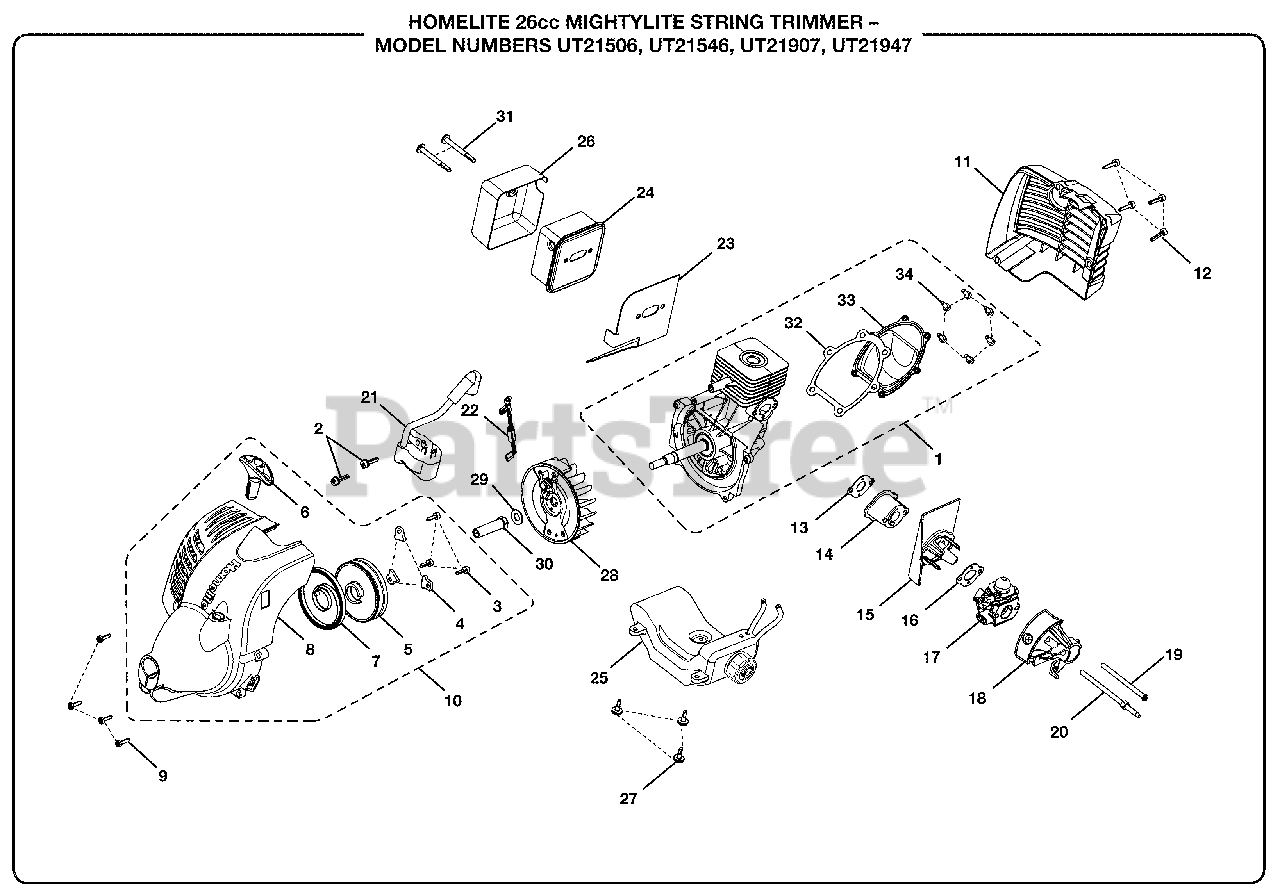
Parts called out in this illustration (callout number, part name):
1	Short Block Assembly
2	Screw (M4 x 19 mm)
3	Screw (M4 x 14 mm)
4	Pulley Retainer
5	Starter Pulley Assembly
6	Pulley Handle
7	Spring & Container Assembly
8	Front Housing
9	Screw (M4 x 16 mm)
10	Front Housing Assembly
11	Rear Housing
12	Screw (M4 x 8 mm)
13	Intake Gasket
15	Heat Dam Deflector
16	Carburetor Gasket
17	Carburetor
18	Choke Base
19	Screw (M5 x 70 mm)
20	Double Sided Hex Bolt
21	Ignition Module
22	Lead Assembly
23	Muffler Gasket
24	Muffler Assembly
25	Fuel Tank Assembly w/Cap (UT21506 & UT21546)
26	Heat Shield
27	Screw (M4 x 10 mm Shoulder)
28	Flywheel Assembly
29	Washer
30	Drive Connector
31	Screw (10-24 x 2-3/16 in.)
32	Gasket
33	Crankcase Cover
34	Screw (M4 x 12 mm)
